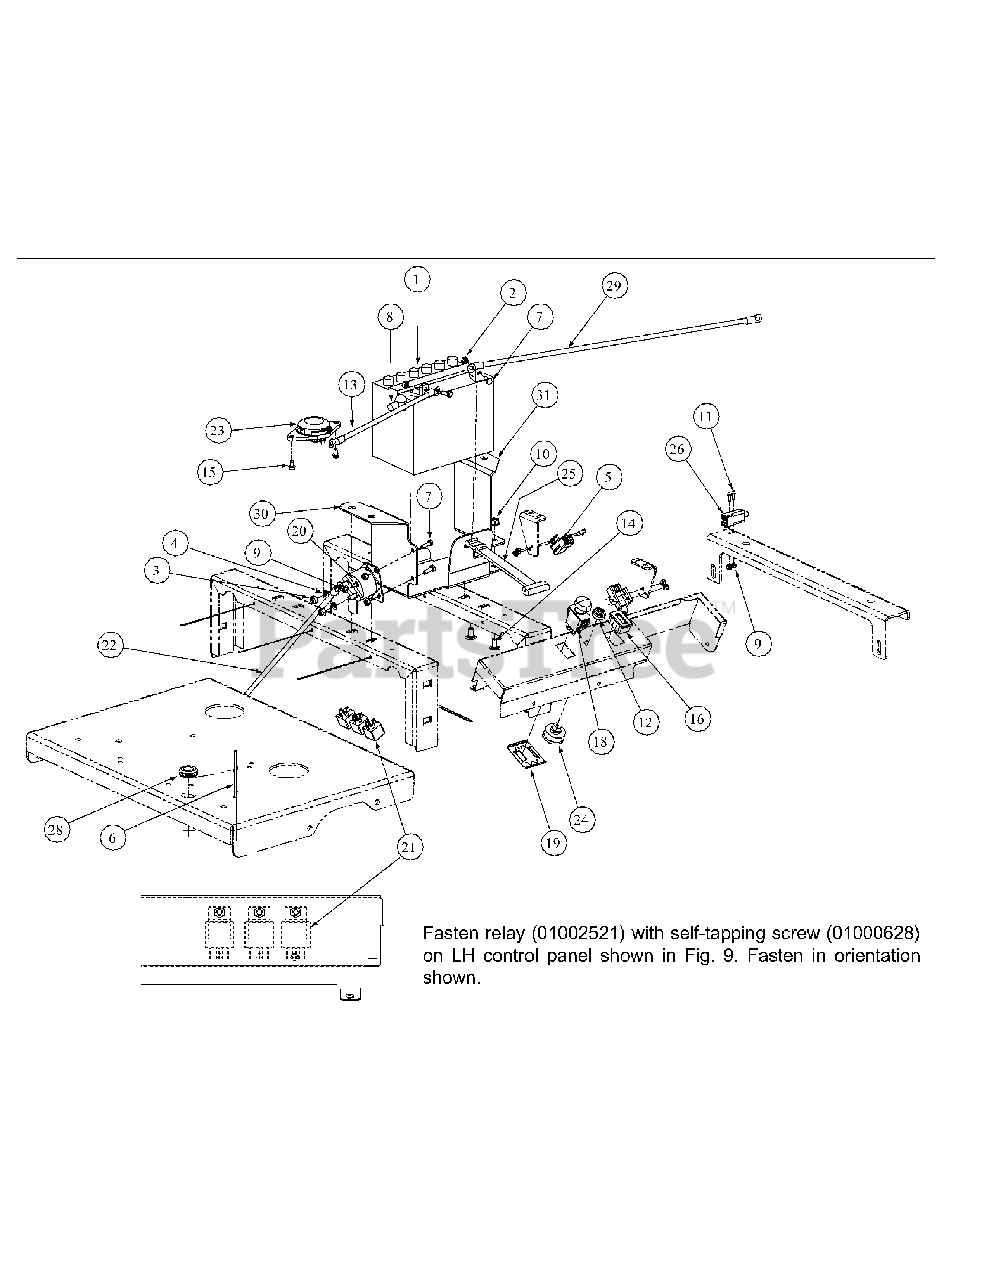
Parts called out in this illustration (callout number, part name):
1	Battery
2	Nut, Lock, Nylon Insert, 1/4-20
3	Nylock Nut, 5/16-18
4	Lock Washer, 5/16
5	Switch, Safety
6	Tie, Cable, 3/16 x .05 x 7.4"
7	Screw, Hex, Cap, 1/4-20 x .75
8	Boot, 1" OD Rubber Battery-PST, Red
9	Nut, Lock, Nylon Insert, #10-32
10	Nut, Hex, Flange Lock, 3/8-16
11	Screw, Phillips Head, Machine, 10-32 x 5/8
12	Nut, W/Cap, 5/8-32 Ignition
13	Cable, Battery, Red, 15"
14	Carriage Bolt, 3/8-16 x .75 LG.
15	Screw, TT, 1/4-20, .500, Hex Index Washer
16	Meter, Hour
17	Hourmeter, Harness
18	Switch, Electric, PTO
19	Bracket, PTO Switch Retainer
20	Solenoid Magnetic Switch
21	Relay, 12V 40A
22	Cable, Battery Red, 32"
23	Switch, Seat
24	Switch, Ignition, 6 Pin
25	Strap, Battery
26	Switch, Plunger
27	Harness Assembly
28	Grommet, .75 ID
29	Cable, Battery Black, 24"
30	Mount Bracket, Battery
31	Mount Bracket, Battery
32	Harness Adaptor
